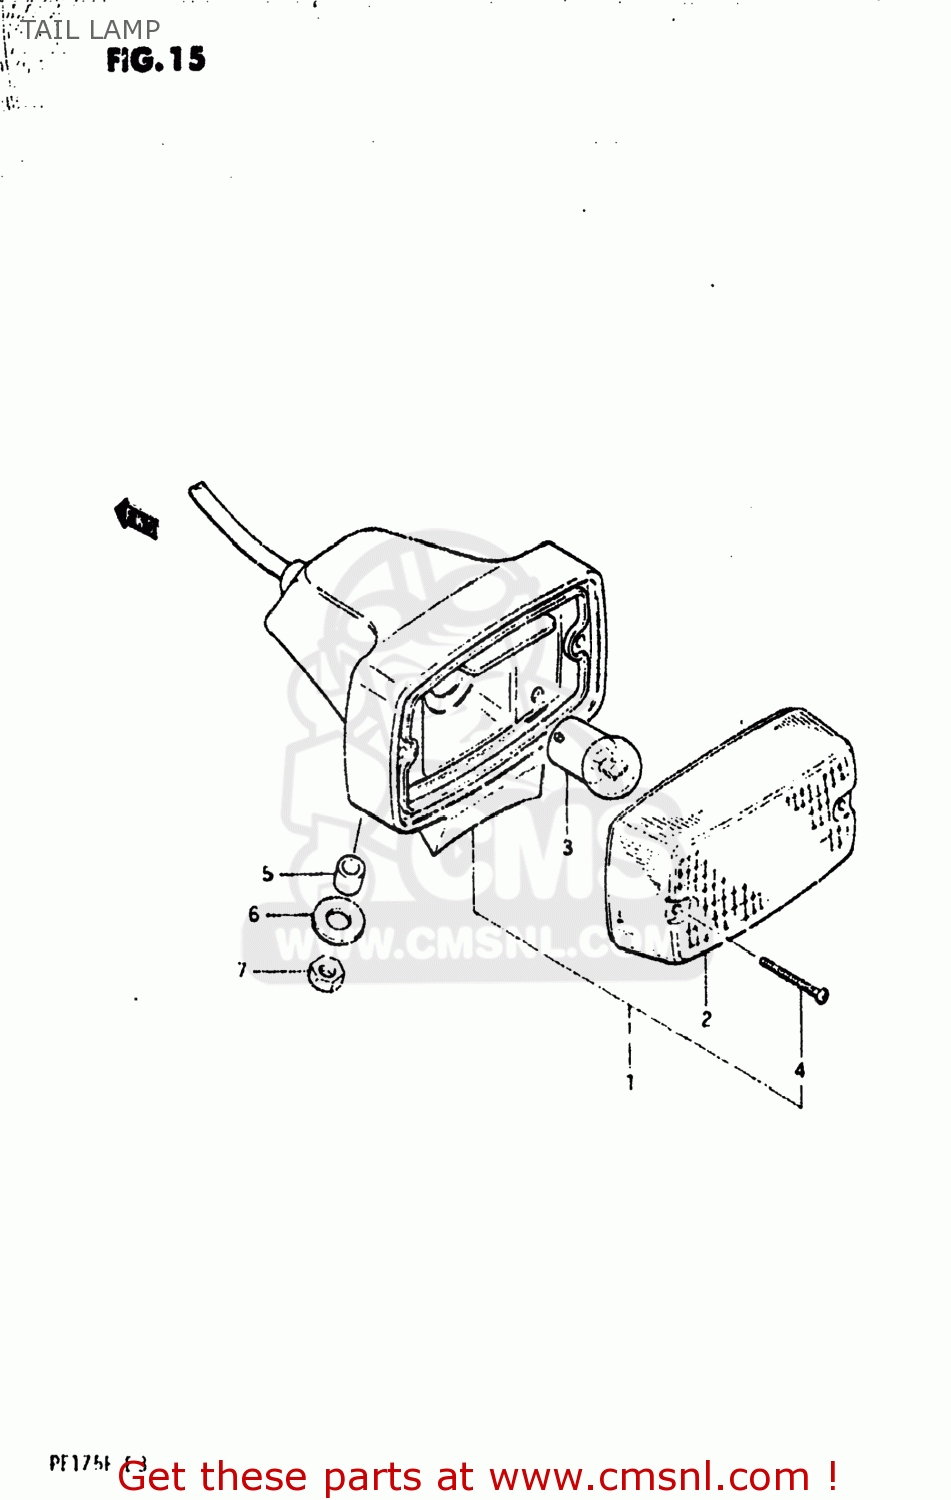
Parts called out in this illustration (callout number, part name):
1	LAMP ASSEMBLY,TAIL
2	LENS
3	BULB(6V5W,TOKAI DENSO)
4	SCREW,REAR COMBINATION LAMP LENS
5	SPACER (6.1X9X9)
6	WASHER
7	NUT
